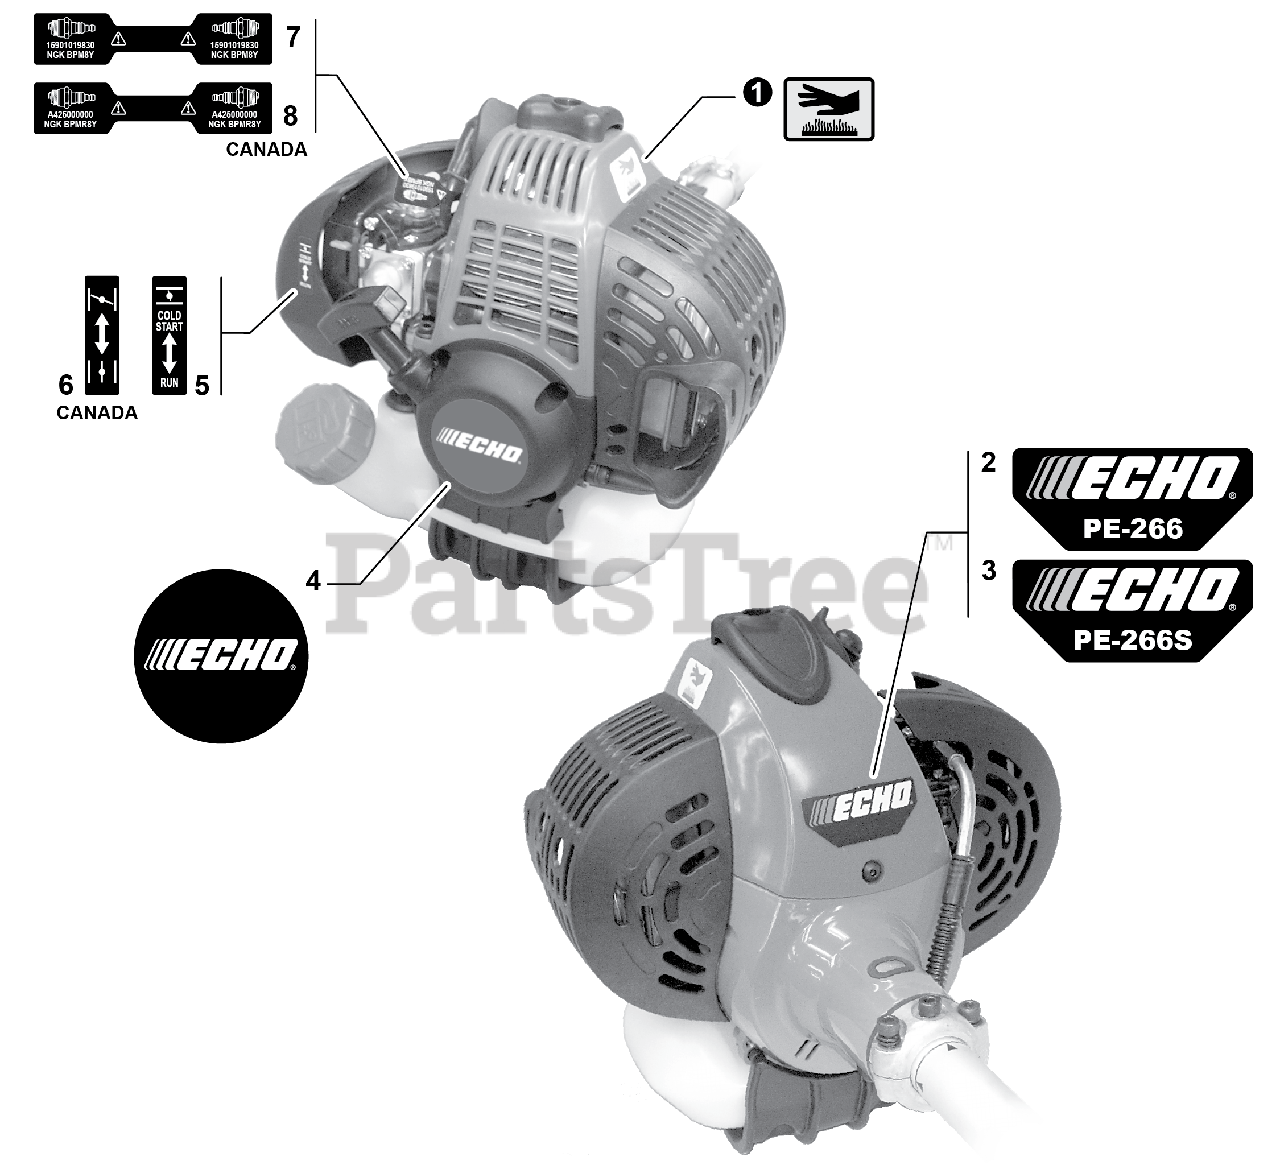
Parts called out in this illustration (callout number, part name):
1	LABEL, CAUTION - HOT
2	LABEL - MODEL PE-266
3	LABEL - MODEL PE-266S
4	LABEL, ECHO
5	LABEL, CHOKE
6	LABEL, CHOKE
7	LABEL, SPARK PLUG - BPM8Y
8	LABEL, SPARK PLUG - BPMR8Y
